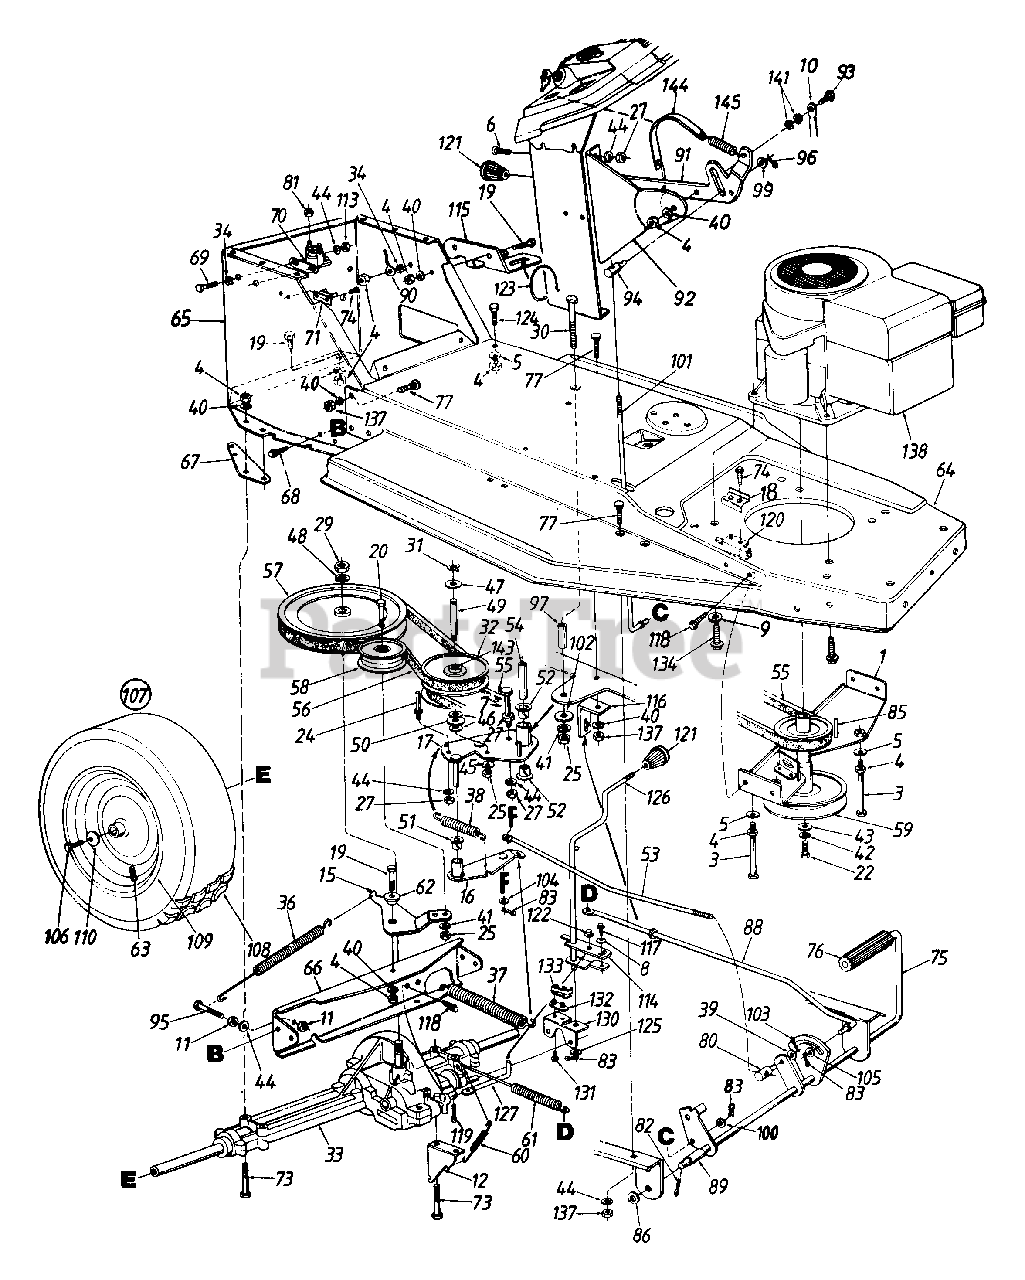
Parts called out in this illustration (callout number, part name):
1	Engine Pulley Belt Guard Ass'y.
3	Hex Bolt 5/16-18 x 51/4" Lg.
4	Hex Nut 5/16-18 Thd.
5	Bell-Wash..345" I.D. x .88
6	Truss-Mach. Scr. 1/4-20 x .50"
7	Hex Bolt 1/4-20 x 3.5" Lg.
8	Bell-Wash..265" I.D. x .75
9	Fl-Wash. 3/8" I.D.
10	Speed Selector Brace
11	Hex Nut 1/4-28 Thd.
17	Variable Speed Brkt. Ass'y.
18	Switch Plate
19	Hex Bolt 5 16-18 x .75" Lg.
20	Hex Bolt 3/8-24 x 2.0" Lg. Gr. 5
22	Hex Bolt 7/16-20 x 1,5" Lg.
24	Belt Guard Pin
25	Hex Nut 3/8-24 Thd.
27	Hex Nut 1/4-20 Thd.
29	Hex Jam Nut 9/16-18 Thd.
30	Hex Bolt 3/8-24 x 3.75" Lg.
31	Snap Ring
32	Variable Speed Pulley Ass'y.
34	Ext. L-Wash. 5/16" I.D.
36	Extension Spring 6.12" Lg.
37	Extension Spring 7.58" Lg.
38	Extension Spring 2.59" Lg.
39	Fl-Wash..385" I.D. x.620"
40	L-Wash. 5/16" I.D."
41	L-Wash. 3/8" I.D.
42	L-Wash. 7/16" I.D.
43	Fl-Wash..450" I.D. x 1.25"
44	L-Wash. 1/4" I.D.
45	Bell-Wash..39" I.D. x 1.13"
46	Fl-Wash..56" I.D. x 1.0" O.D.
47	Washer "Teflon" .565 I.D.
48	Bell-Wash. 9/16" I.D. x 1.125" O.D.
49	Shaft .56" Dia. x 3.875" Lg.
50	Thrust Brg. 1.25 O.D.
51	Flanged Nyliner Brg.
52	Nyliner Flanged Brg.
53	Speed Control Rod
54	Spacer
55	V-Belt
56	V-Belt
57	V-Pulley 8" Dia.
58	Idler Pulley 3-1/8" Dia.
59	Dbl. Pulley 6.0" Dia. x 3.56"
60	Extension Spring 3.18" Lg.
61	Extension Spring 7.08" Lg.
62	Shld. Spacer .500" Dia.
63	Air Valve
66	Transaxle Support Brkt.
69	Hex Bolt 1/4-20 x .62" Lg.
70	Solenoid
71	Circuit Breaker
73	Hex Bolt 5/16-18 x 2.75" Lg.
74	Truss Mach. B-Tap Scr. #10 x .50" Lg.
75	Foot Pedal Rod Ass'y.
77	Ribbed Neck Bolt 5/16-24 x .84"
80	Ferrule
81	Hex Sems Nut 1/4-20 Thd.
82	Cot-Pin 1/8" Dia. x 1.25" Lg.
83	Cot-Pin 3/32" Dia. x .75" Lg.
85	Sq. Key 1/4 x 2.0" Lg.
86	Fl-Wash..635" I.D. x 1.0"
88	Brake Rod
89	Spacer 5/8" I.D. x 1.2" Lg.
90	Ground Wire 7.25" Lg.
91	Speed Selector Lever
92	5 Speed Selector Brkt.
93	Shld. Bolt .437" Dia. x .47" Lg.
94	Ferrule
95	Hex Bolt 1/4-28 x 1.25" Lg.
96	Intern. Cot-Pin 5/16" Dia.
97	Spacer.375" I.D. x.625"
99	Fl-Wash..344" I.D. x .62"
100	Fl-Wash..25" I.D. x .62" O.D.
101	Speed Control Rod
102	Fl-Wash. 3/8" I.D. x 1.25" O.D.
103	Cot-Pin 1/8" Dia. x 1.0" Lg.
104	Fl-Wash..34" I.D. x.68"
105	Fl-Wash..34" I.D.
106	Hex L-Bolt 5/16-24 x .75" Lg.
110	Bell-Wash..345" I.D. x .88"
113	Hex Jam Nut 1/4-20 Thd.
114	Shift Lever Adjusting Link
115	Shift Lever Spring Brkt.
118	Hex Wash. Hd. Tap Scr. 1/4-20 x .5" Lg.
119	Intern. Cotter Pin
120	Safety Switch (Clutch)
121	Knob
122	Retaining Ring
123	Compression Spring 1.5" Lg.
124	Hex Wash. Hd. Scr. 5/16-18 x 7/8" Lg.
125	Fl-Wash..469" I.D. x .88"
130	Shift Lever Support
131	Hex Wash. Hd. #8 x .50" Lg.
132	Insulator Nut Plate
133	Spring Switch
134	Hex Tap Scr. 3/8-16 x 1.25"
137	Hex Nut 5/16-24 Thd.
138	Engine
141	Wave Wash..445" I.D.
143	Needle Brg.
144	7-Speed Indicator Strip
145	Ext. Spring 2.04" Lg.
